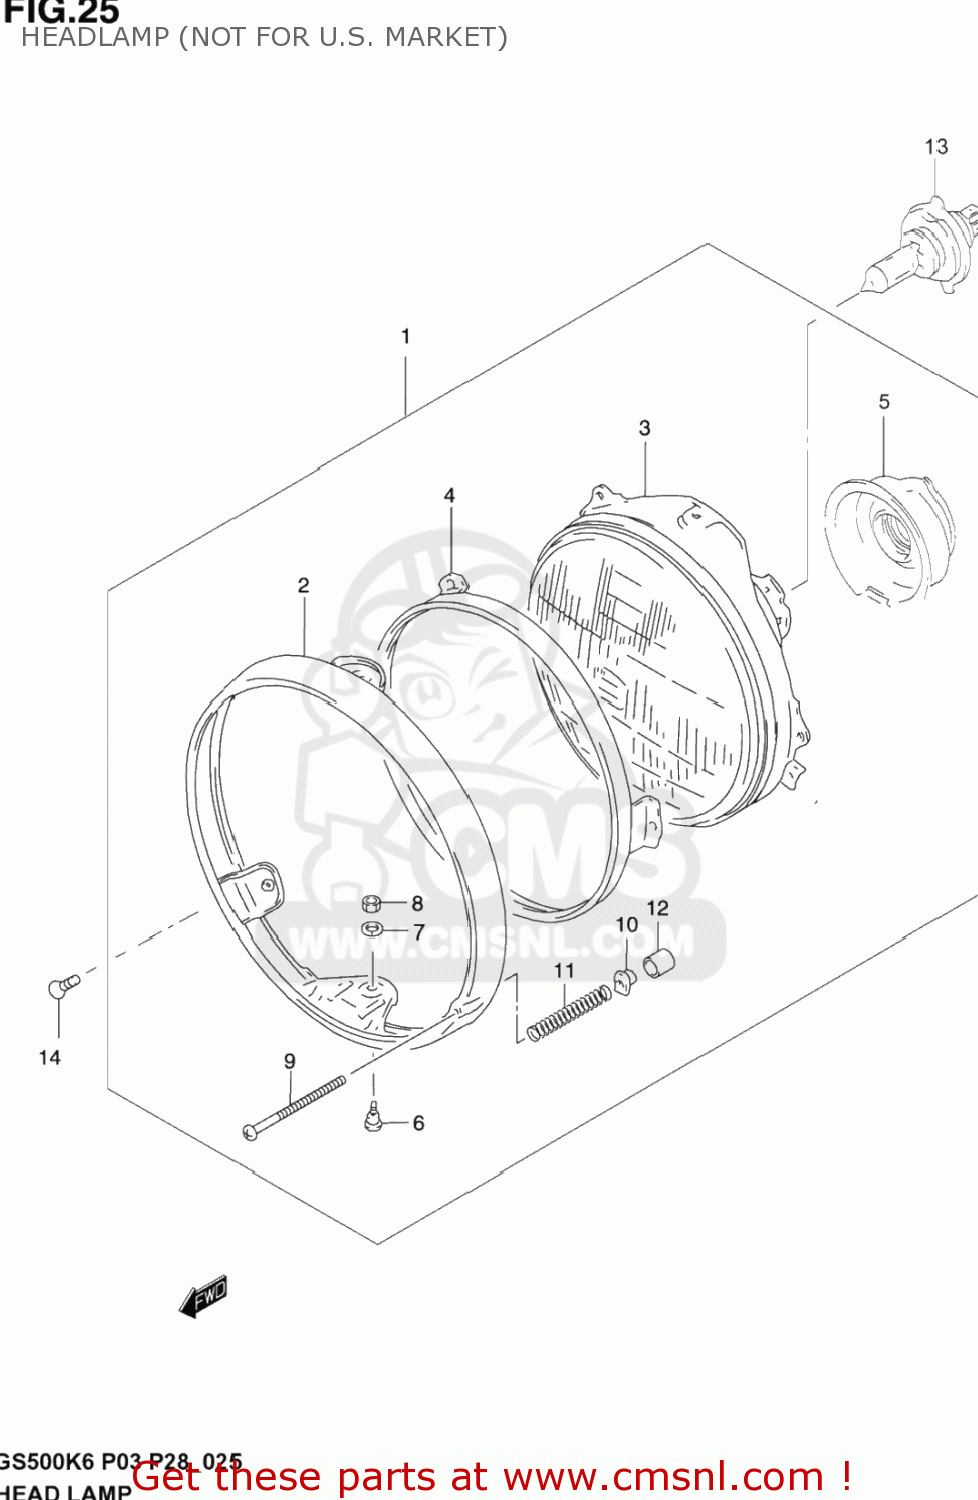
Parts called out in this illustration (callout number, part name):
1	HEADLAMP ASSY
2	RIM,HEADLAMP
3	LAMP UNIT
4	RING
5	COVER,SOCKET
6	H/LAMP LENS UNIT FITING SCRE
7	WASHER,LOCK
8	NUT
9	SCREW
10	NUT
11	SPRING,ADJUSTING
12	CAP,SCREW
13	BULB(12V60/55W,H4)
14	SCREW(5X12)
